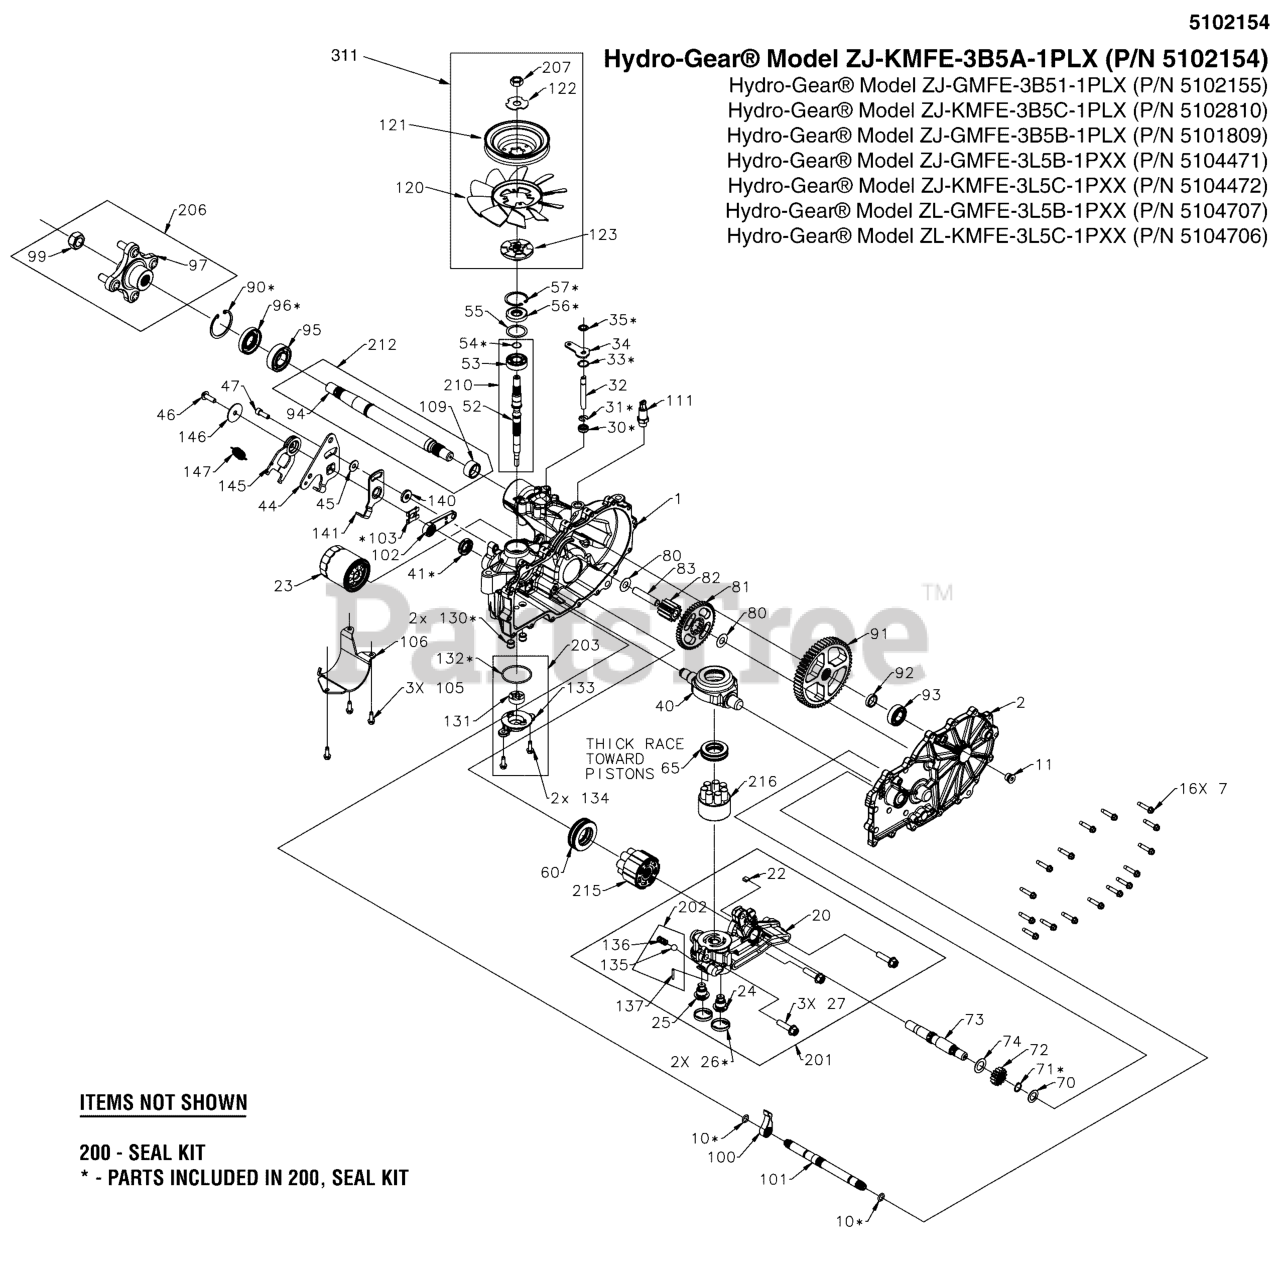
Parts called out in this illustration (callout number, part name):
23	FILTER, OIL, ZT2800
41	SEAL, CONTROL ARM, 18X32X7, #51140
56	OUTPUT SHAFT SEAL, 17X40X7, HR #51161
57	RING, RET 2.06 INT,
95	BEARING BALL, 1.0 X 52 X 15 OPEN 6205M
96	SEAL, LIP, AXLE, #53699
120	FAN
121	PULLEY, 4.5 INCH, HG #52364
121	PULLEY, HG #53804
122	WASHER, ZT5400, SLOTTED
123	HUB
200	KIT SEAL
203	KIT, CHARGE PUMP, ZT2800, ZT3100
206	HUB, ASM, TRANS 5101188/89 & 5102154/55
207	NUT, ZT5400
210	KIT, INPUT SHAFT
311	KIT, FAN AND PULLEY (72134)
1000	KIT, PLUG, BRAKE BORE, OUTBOARD
1001	KIT, PLUG, BRAKE BORE, INBOARD
